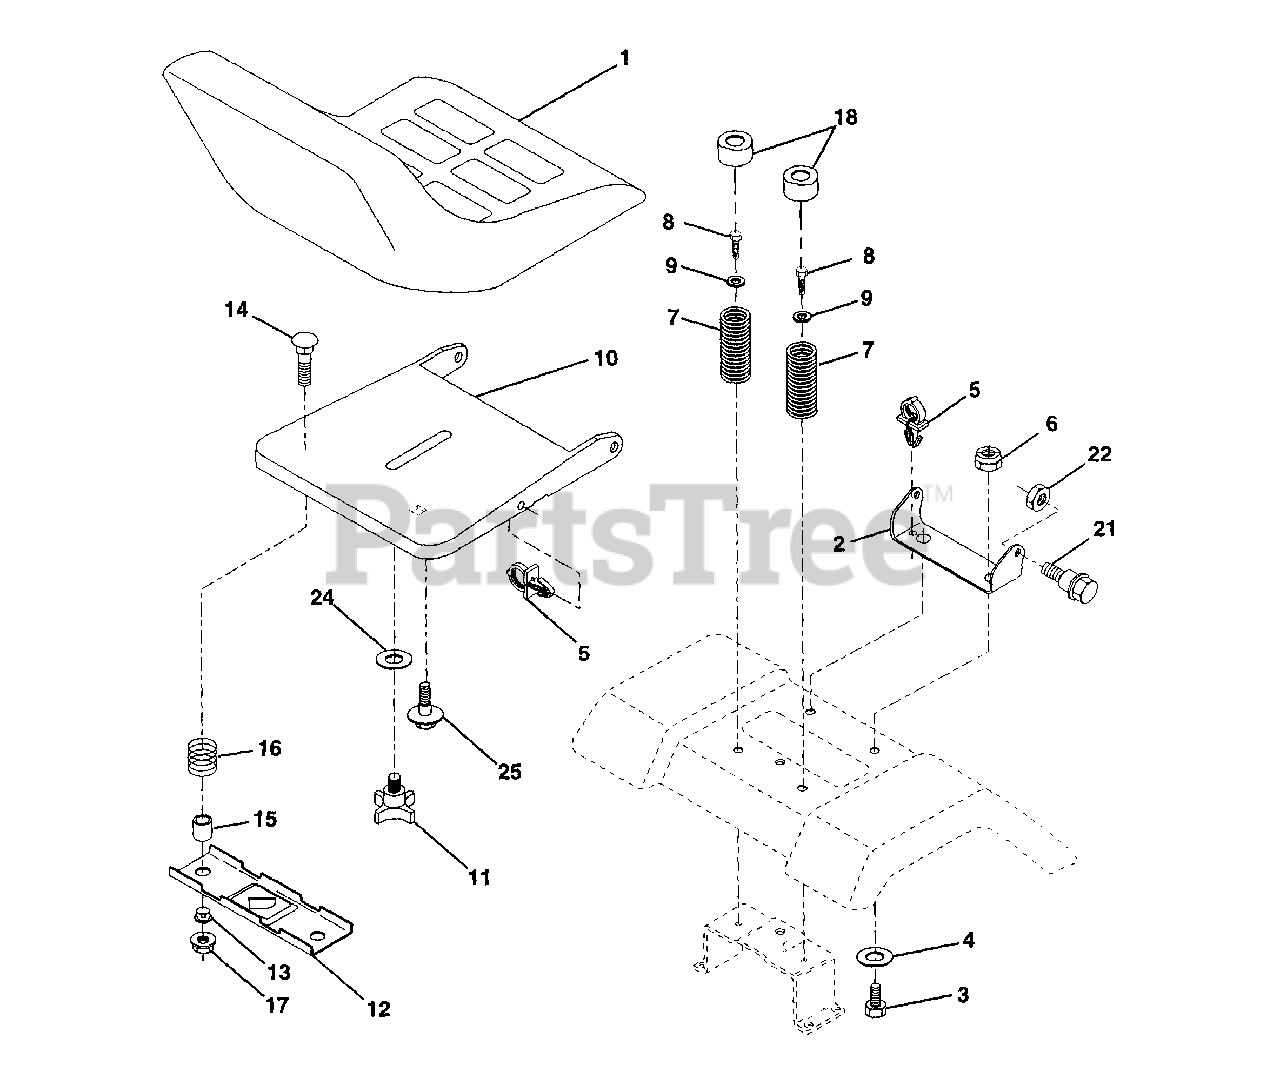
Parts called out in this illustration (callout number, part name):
1	Seat
2	Bracket Pivot Seat 8 720
3	Bolt Fin Hex 3/8-16unc X 1
4	Washer 13/32 X 1 X 10 Ga
5	Clip Push-In
6	Nut Hex w/Ins. 3/8-16 Unc
7	Spring Seat Cprsn 2 250 Blk Zi
8	Screw Thdrol 3/8-16 X 1 Ty-tt
9	Washer 13/32 X 1 X 14 Ga.
10	Pan, Seat
11	Knob, Seat
12	Bracket Mounting Switch
13	Bushing Snap Blk Nyl 50 Id
14	Bolt Rdhd Sqnk 1/4-20x1-3/8
15	Spacer Split 28x 96 Yel Zinc
16	Spring Cprsn 1 27 Blk Pnt
17	Nut Lock 1/4 Lge Flg Gr 5 Zinc
18	Cap Spring, Seat Blk 1.75 x 1.0
21	Bolt Shoulder 5/16-18 Unc
22	Nut Hex Lock W/Ins 5/16-18
24	Washer 17/32 X 1-3/16 X 12 Ga.
25	Bolt Shoulder 5/16-18 X 62
